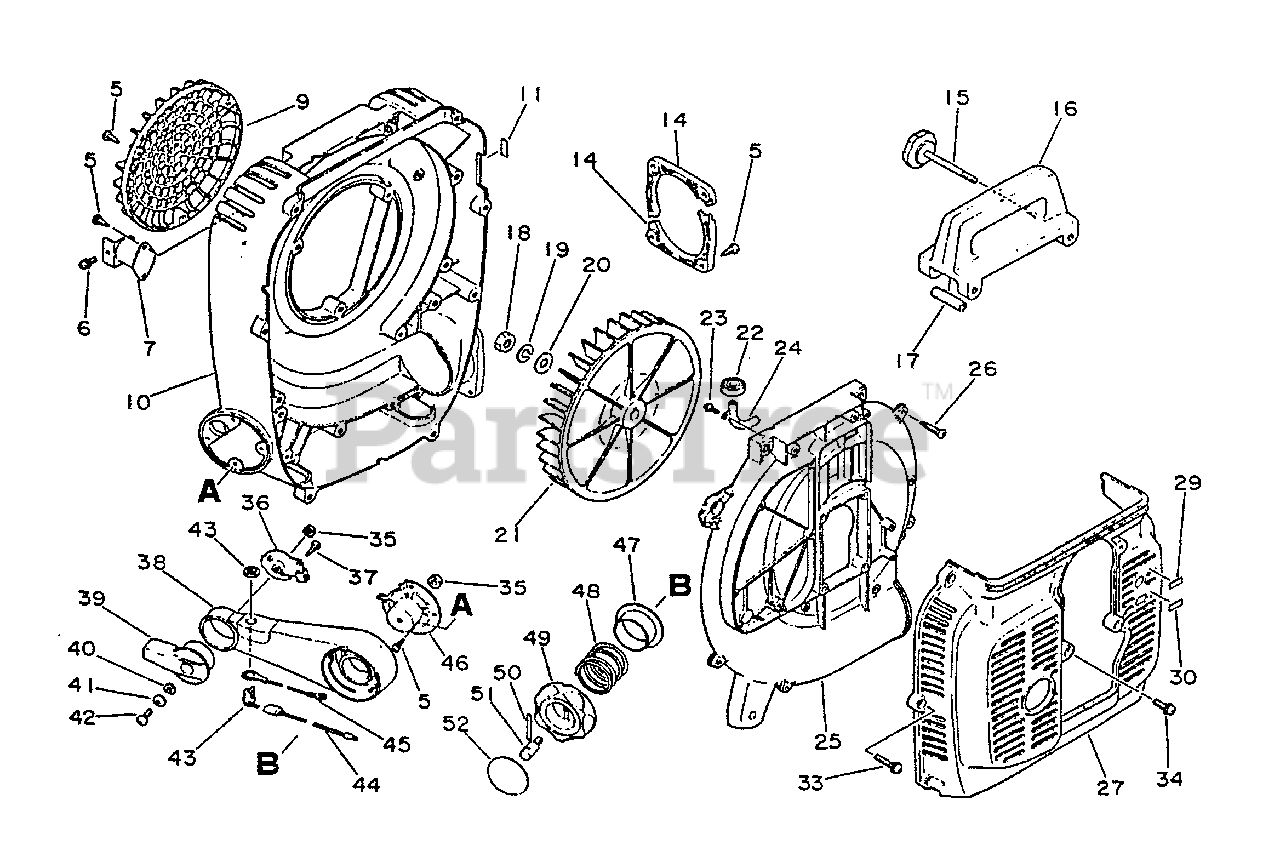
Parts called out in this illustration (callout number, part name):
5	SCREW - 5X12
6	SCREW - 5X12
9	GUARD, DEBRIS
10	COVER, FAN - INNER
11	LABEL - CHOKE
14	BRACKET
15	BOLT
18	NUT - 10
19	LOCKWASHER - 10
20	WASHER - 10
23	SCREW - 4X10
24	PIPE - INTAKE
25	COVER, FAN - OUTER
26	SCREW - 5X25
27	COVER, ENGINE
29	LABEL - IDLE
30	LABEL - CAUTION
33	SCREW - 5X20
34	SCREW - 5X15
35	LOCKNUT - 6
36	BRACKET, THROTTLE
37	SCREW - 4X10
38	MOUNT, THROTTLE LEVER
39	TRIGGER, THROTTLE
40	WASHER - 6
41	WASHER
42	SCREW - 6X20
43	IGNITION SWITCH ASSY
44	LEAD - IGNITION
45	LEAD - GROUND
46	PLATE
47	SEAT, SPRING
52	LABEL - IDLE
